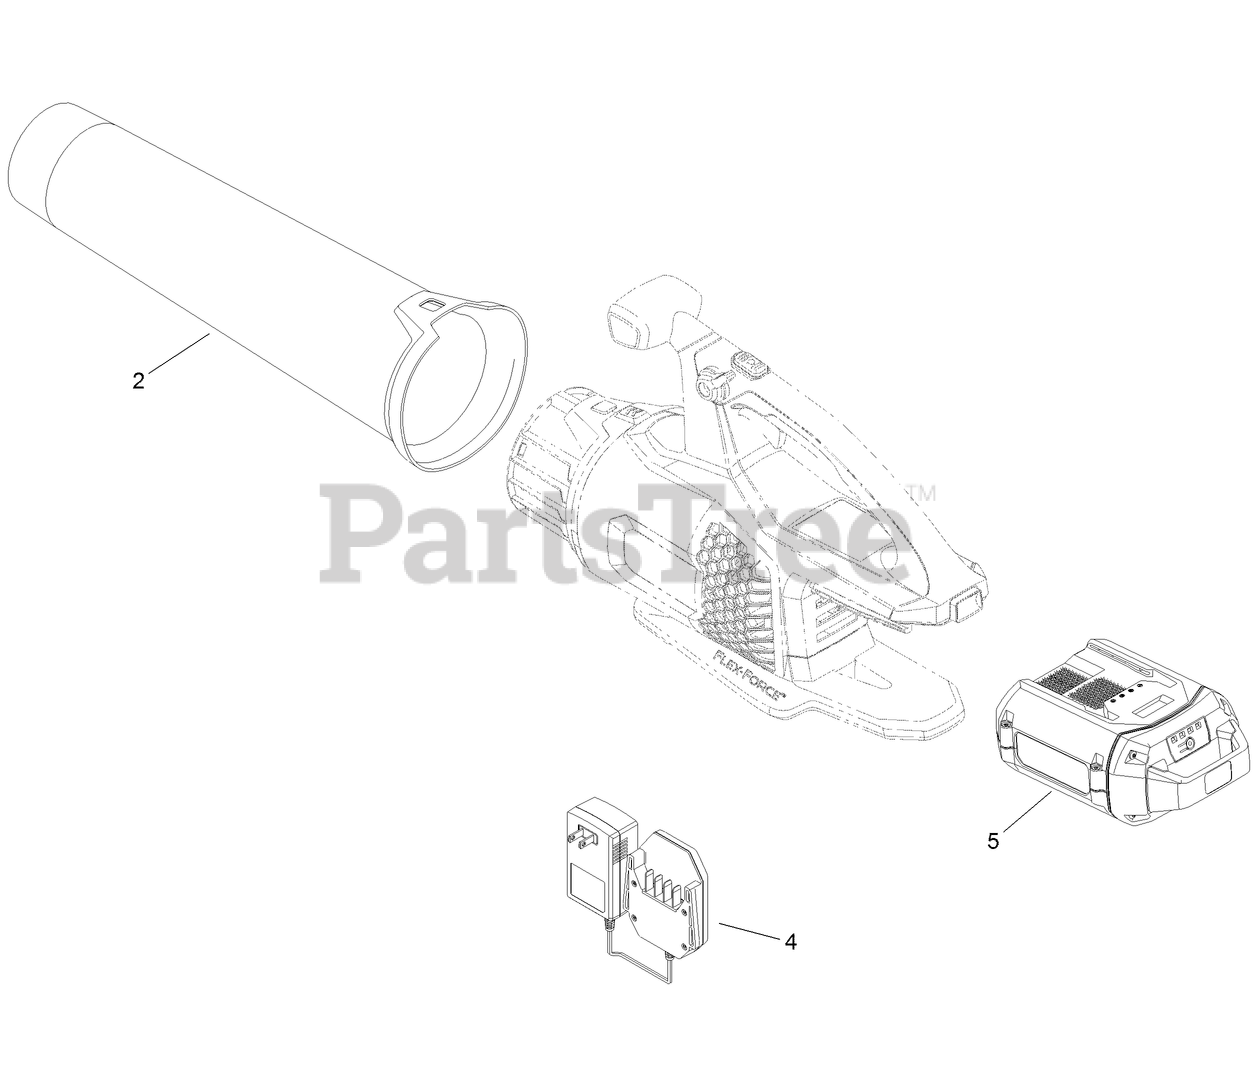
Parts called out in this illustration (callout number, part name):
2	TUBE-BLOW
4	CHARGER-BATTERY, 60V 1 AMP
5	BATTERY-60V 2.0AH
